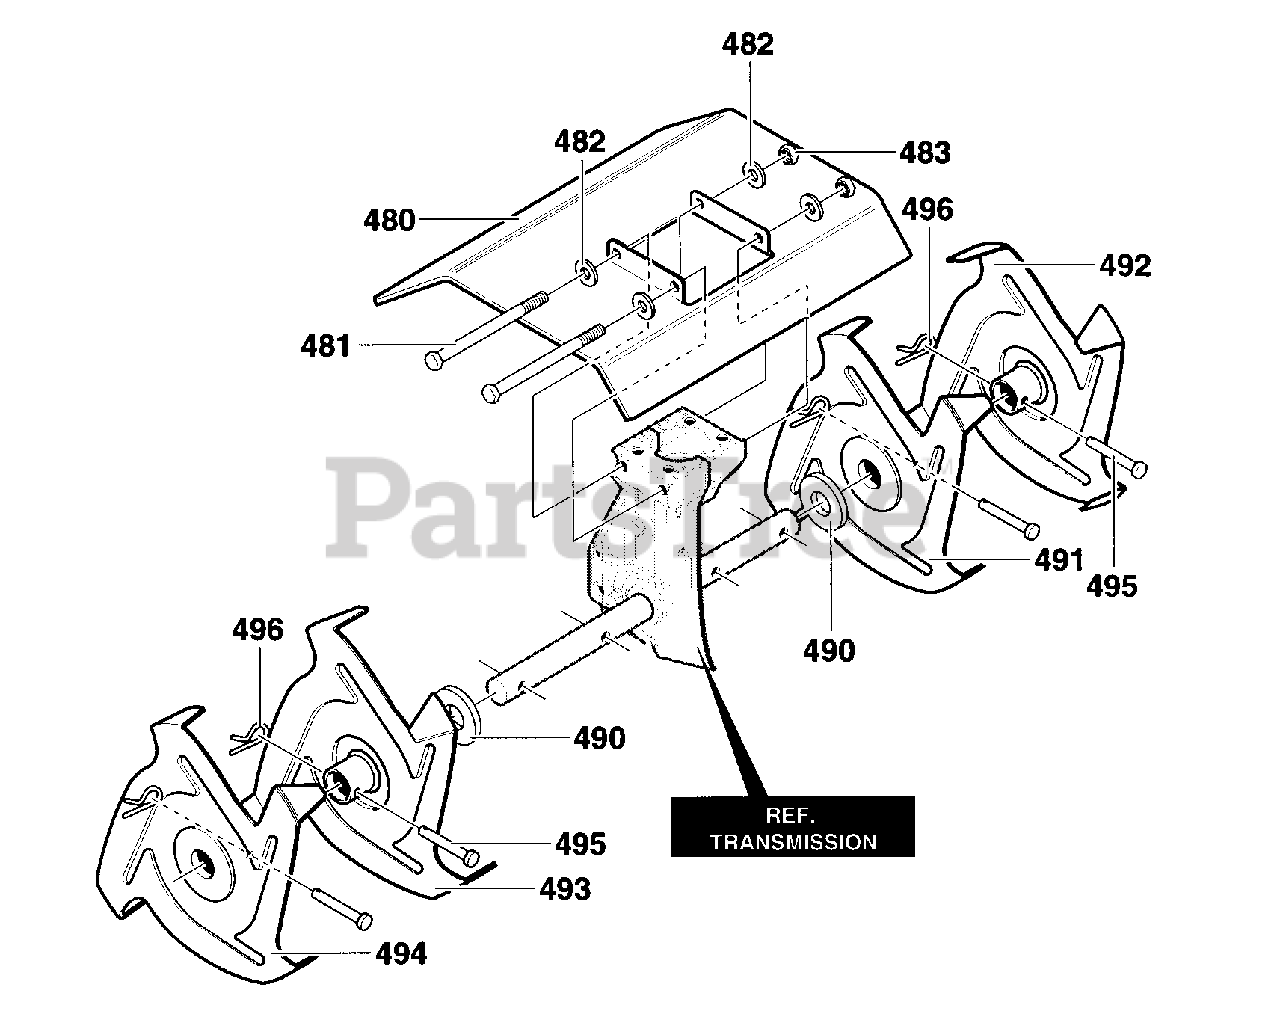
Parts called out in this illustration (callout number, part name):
480	SHIELD, TINE
481	SCREW, 1/4-20X5.00 HHC
482	WASHER, FLAT .281X .63X.065
483	NUT, 1/4-20 REGHEXCTRLK
490	WASHER, FELT.68X1.46X.12 WOOL
491	TINE, ASSY INNER LH
492	TINE, ASSY OUTER LH
493	TINE, ASSY INNER RH
494	TINE, ASSY OUTER RH
495	PIN, CLEVIS .31X1.38
496	PIN, HAIR .53DIAX1.62LG
